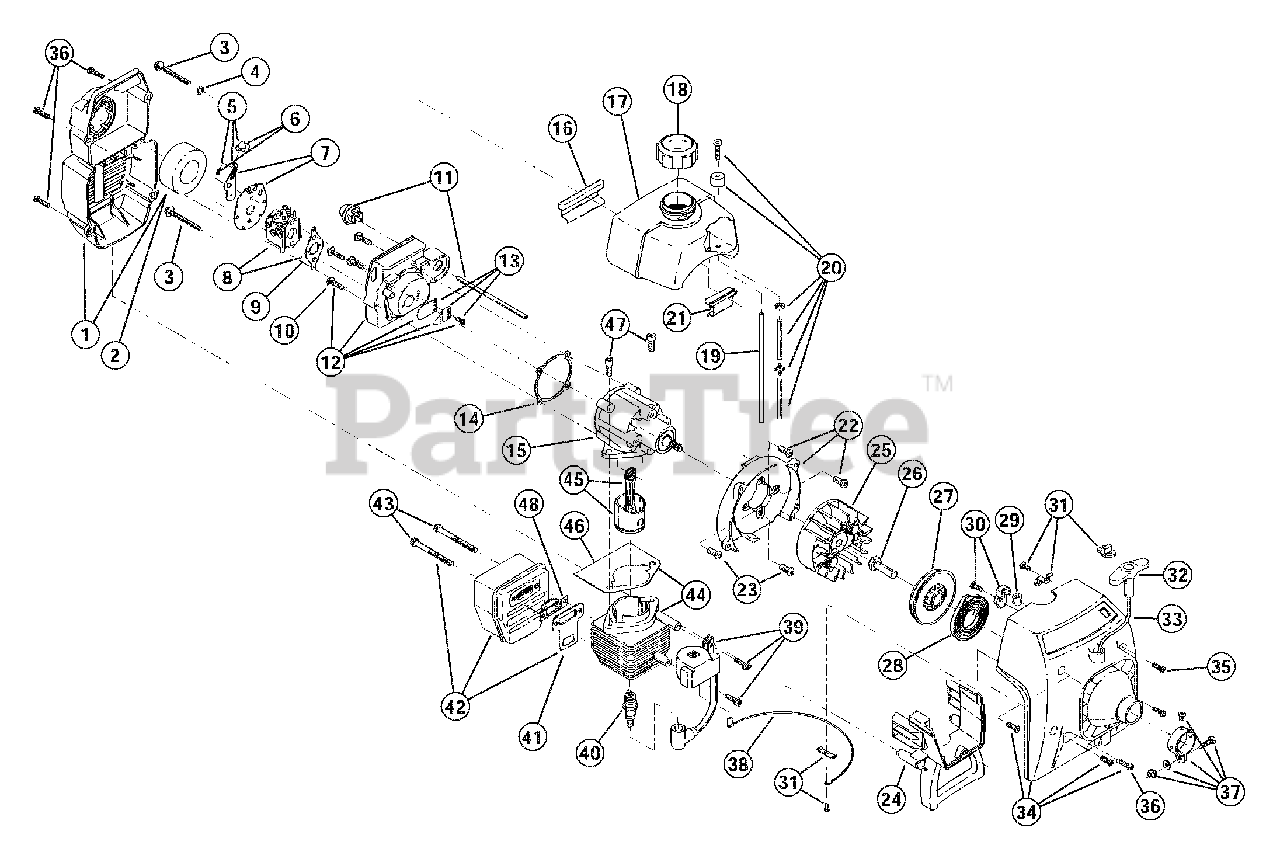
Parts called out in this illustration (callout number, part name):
1	Air Cleaner/Muffler Cover Assembly
2	Air Cleaner Filter
3	Carburetor Mounting Screws
4	Wavey Washer
5	Choke Lever Assembly
6	Choke Knob & Screw
7	Choke Lever & Plate
8	Carburetor Assembly
9	Carburetor Gasket
10	Carb Mount Screw
11	Primer and Hose Assembly
12	Carburetor Mount Assembly
13	Reed Assembly
14	Carburetor Mount Gasket
15	Crankcase Service Assembly
16	Rear Mounting Pad
17	Fuel Tank Assembly
18	Fuel Cap Assembly
19	Fuel Return Line
20	Fuel Line Assembly
21	Front Mounting Pad
22	Shroud Assembly
23	Shroud Screw
24	Shroud Extension and Stand
25	Flywheel Assembly
26	Square Nut Drive
27	Recoil Pulley
28	Recoil Spring
29	Rope Guide
30	Pulley Retainer Assembly
31	Switch Assembly
32	Pull Handle
34	Starter Housing Assembly
35	Housing Screw
36	Cover Screw
37	Upper Clamp Assembly
38	Wire Lead
39	Module Assembly
40	Spark Plug
41	Exhaust Gasket
42	Muffler Assembly
43	Muffler Mounting Bolt Assembly
44	Cylinder Assembly
45	Piston and Rod Assembly
46	Cylinder Gasket
47	Cylinder Bolt
48	Spark Arrestor
